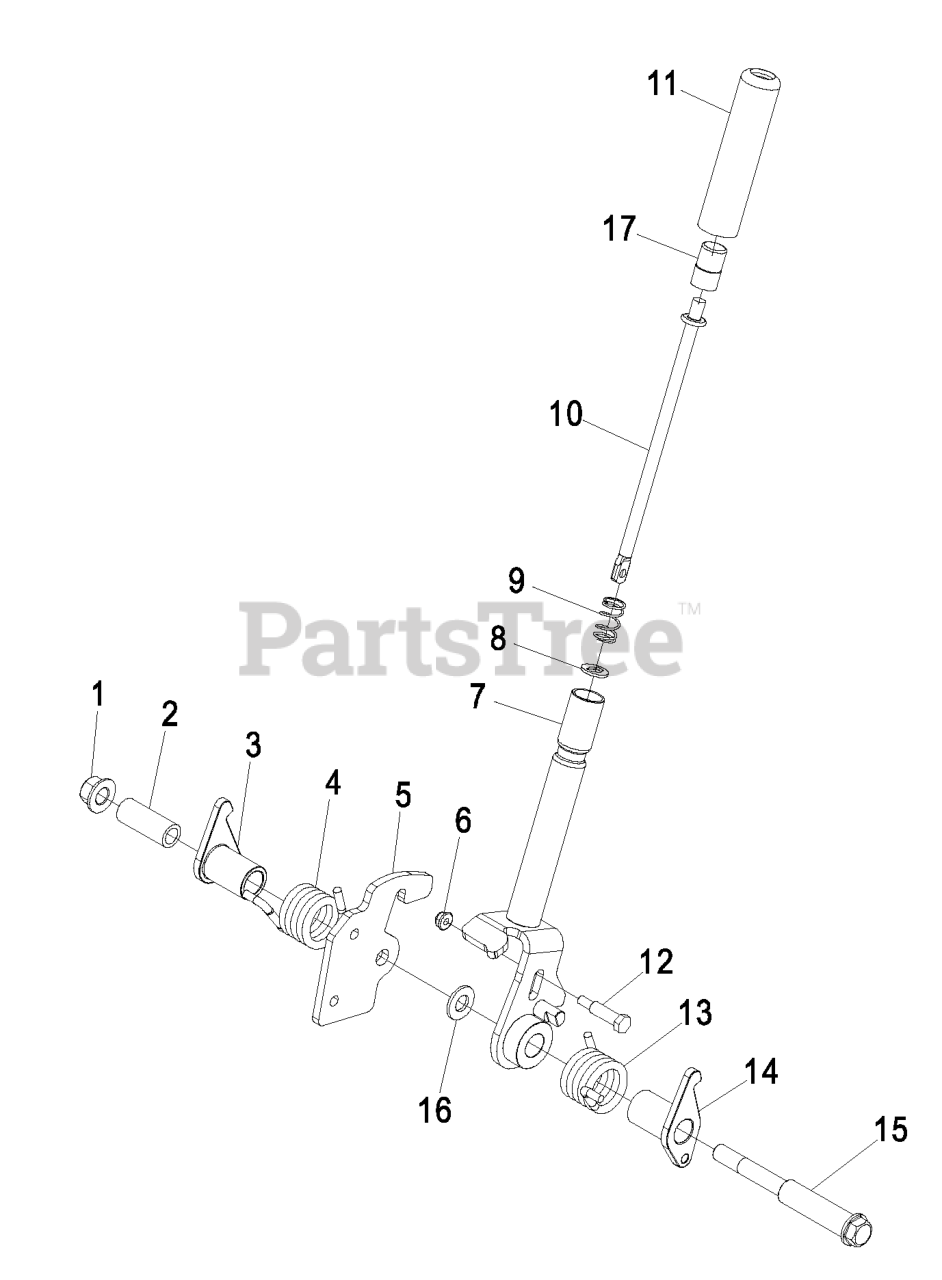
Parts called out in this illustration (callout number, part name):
1	Nut-Lock 1/2-13
3	ARM-BRAKE, LH
4	SPRING-TORSION, RH
5	PLATE-LATCH
7	BRAKE HANDLE ASM
8	WASHER-SPECIAL
9	SPRING-COMPRESSION
10	ROD-RELEASE, BRAKE
12	BOLT-SHOULDER
13	SPRING-TORSION, LH
14	ARM-BRAKE, RH
15	BOLT-SHOULDER
16	WASHER-FLAT
